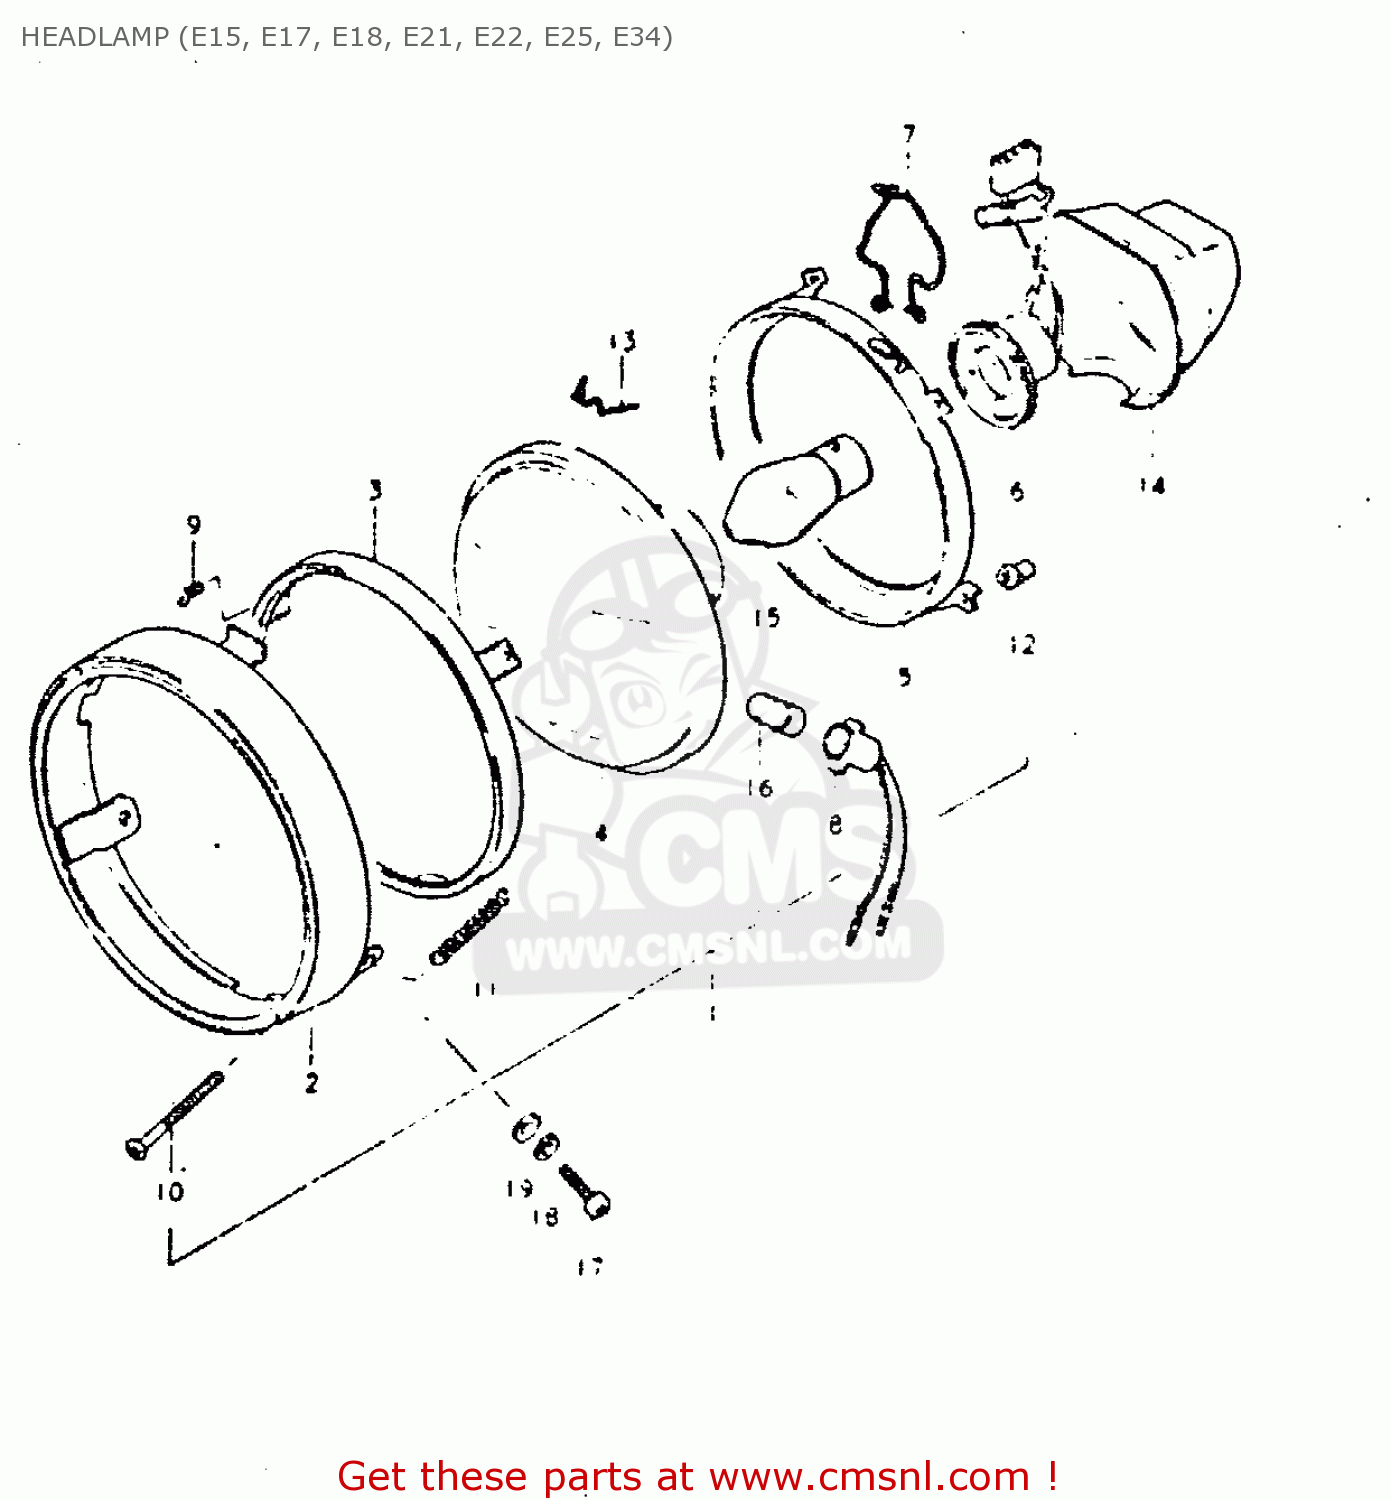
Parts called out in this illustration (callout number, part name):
1	HEADLAMP ASSY
2	RIM
3	RETAINER,HEADLAMP
4	UNIT
5	RING, MOUNTING
6	SOCKET
7	CLAMP,HEADLAMP
8	SOCKET
9	SCREW
10	SCREW,HEADLAMP ADJUST
11	SPRING,ADJUSTING
12	NUT,HEADLAMP ADJUSTER
13	SPRING,HEADLAMP UNIT
14	COVER, SOCKET
15	BULB (6V,35/35W)
16	BULB (6V,4W)
17	SCREW
18	LOCK WASHER
19	WASHER
